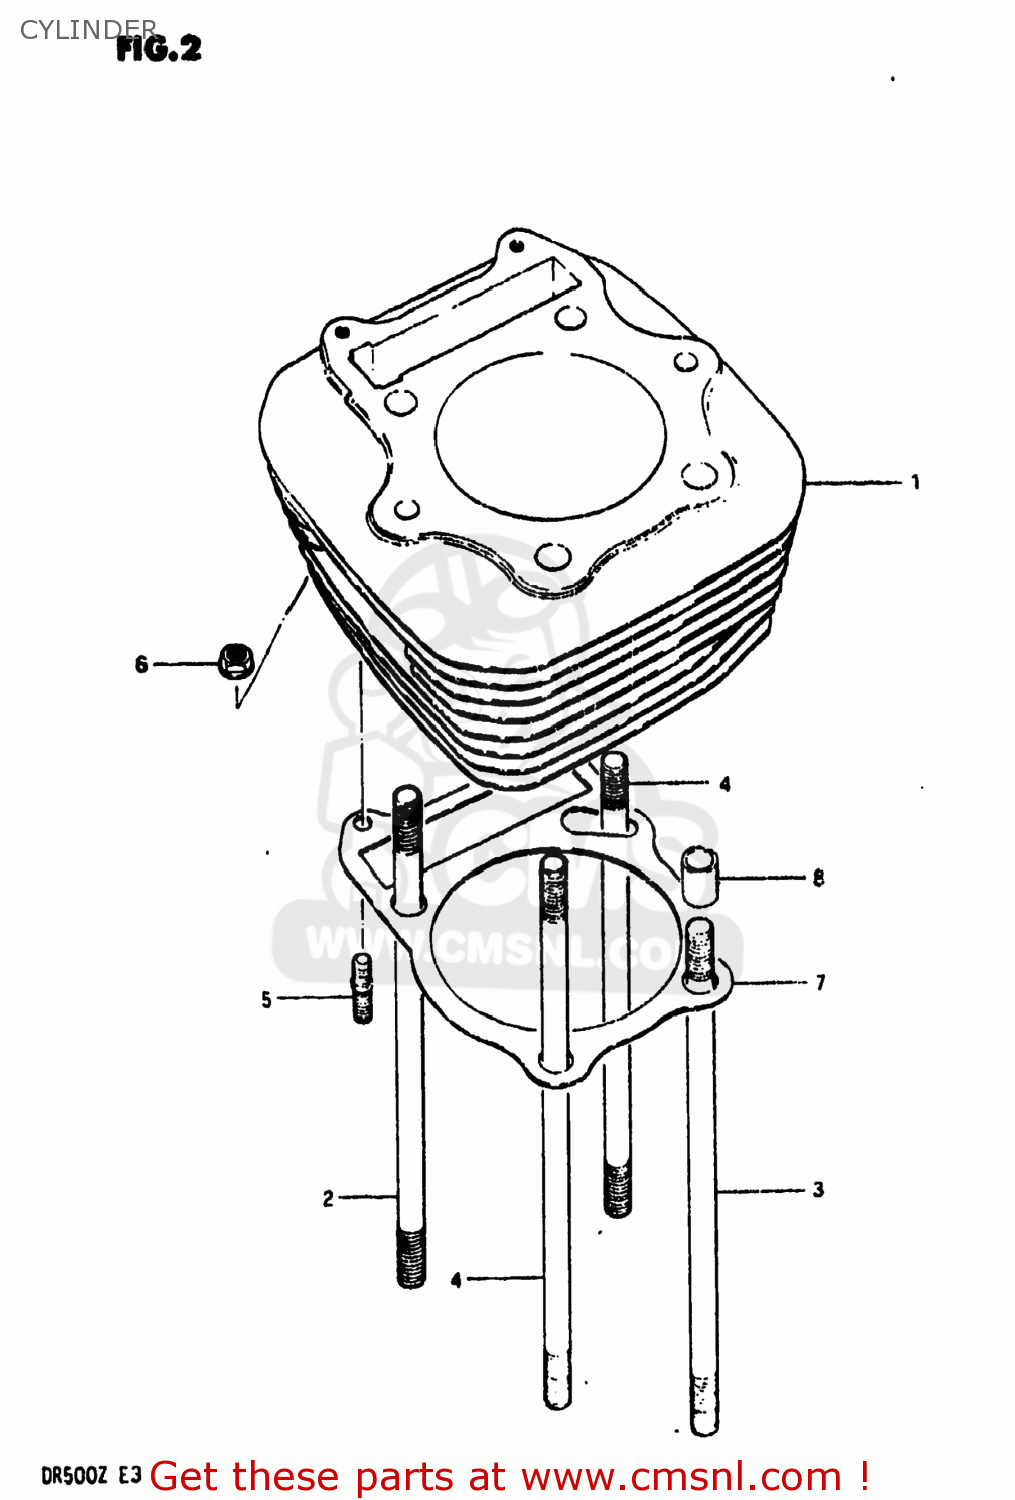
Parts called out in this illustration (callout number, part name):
1	CYLINDER
2	STUD
3	STUD
4	BOLT,STUD
5	STUD 6X25
6	NUT
7	GASKET,CYLINDER (MCA)
8	PIN
